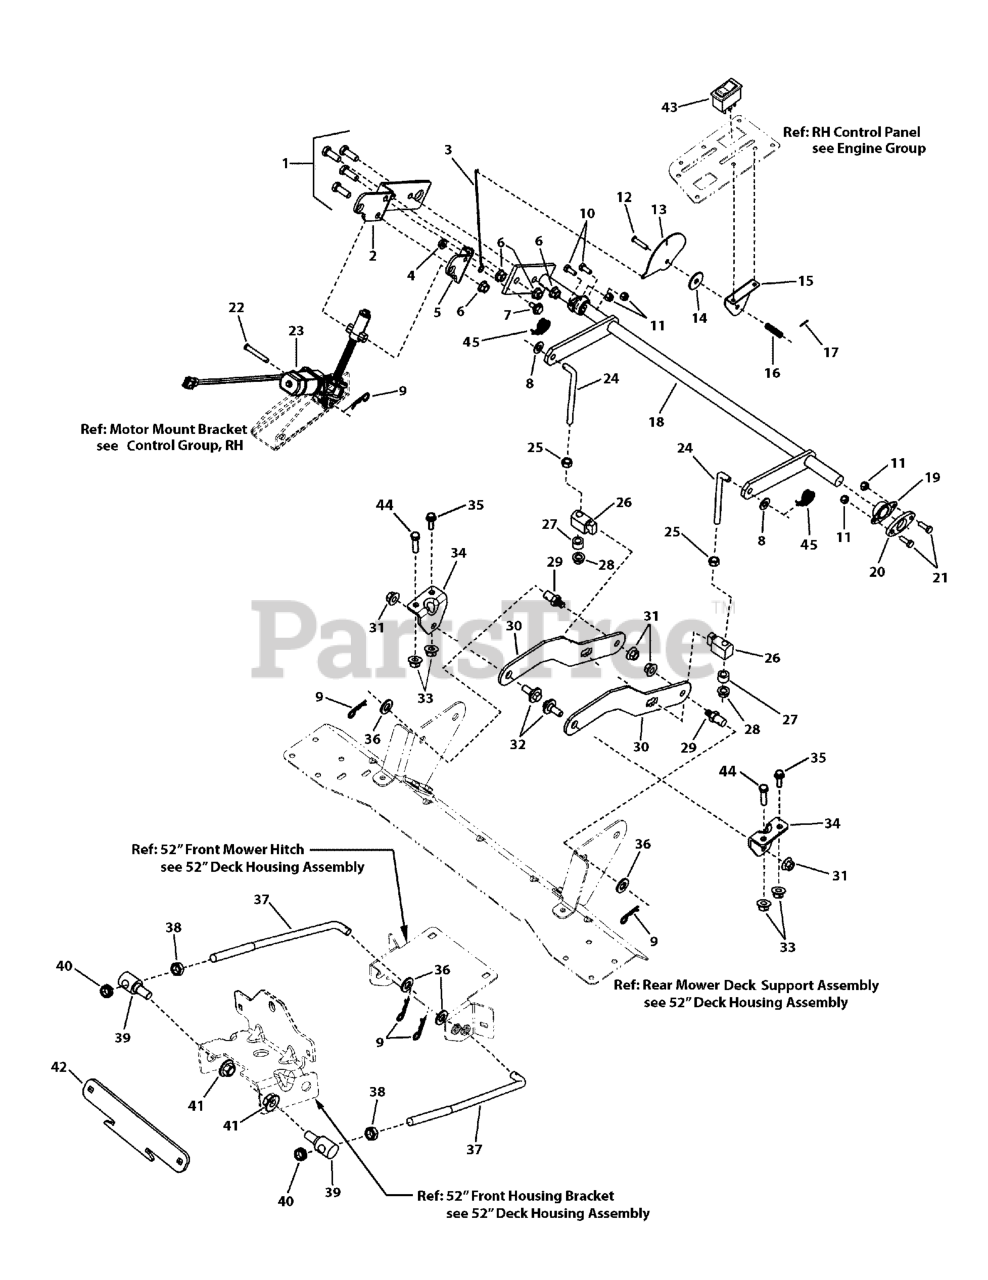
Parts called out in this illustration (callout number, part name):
1	SCREW, 3/8-16 x 1" Hex Head Cap, GR 5, YZ
2	BRACKET, Lift, Deck, Primary
3	ROD, Indicator, Height-Of-Cut
4	NUT, 1/4-20 Hex Flange Lock, GR 5, YZ
5	BRACKET, Lift, Deck, Secondary
6	NUT, 3/8-16 Hex Flange lock, YZ
7	SHOULDER BOLT, 1/4-20 x 3/8"
8	WASHER, 3/8" Flat (SAE)
9	HAIR PIN, 3/32 x 1-1/2" YZ
10	SCREW, 1/4-20 x 5/8" Hex Head Cap, GR 5
11	NUT, 1/4-20 Hex Nyloc, YZ
12	CLEVIS PIN, .25 x 1.09
13	LEVER, Indicator, Height-Of-Cut
14	WASHER, 5/16" Nylon
15	BRACKET, Indicator, Height-Of-Cut
16	SPRING, Compression
17	COTTER PIN, .06 x 1/2" YZ
18	WELDMENT, Deck Lift, 38/42
19	BEARING, Flange, .75 ID PM
20	SPACER, Bearing, .25"
21	SCREW, 1/4-20 x 3/4" Hex Head Cap, GR 5 YZ
22	SHEAR PIN, .248 ID x 1-3/4" Long
23	MOTOR, Actuator, Lift, Deck
24	ROD, Mower Lift (3/8-16 thread) Yellow
25	NUT, 3/8-16 Hex, Black
26	TRUNNION, Powdered Metal, Yellow, Regent
27	SPACER, .385 ID x .6697 OD x .455 Long, PM Yellow
28	NUT, 3/8-16 Hex Flange Esna, Black
29	PIN, 3/8-16 Threaded Shoulder
30	BAR, Rear Lift
31	NUT, 3/8-16 Hex Flange Center Lock, Zinc Plated
32	SHOULDER BOLT, 3/8-16 x .94, BZ
33	NUT, 5/16-18 Flange Lock, YZ
34	BRACKET, Deck Hanger
35	BOLT, 5/16-18 x 5/8" Hex Flange lock, GR 5, YZ
36	WASHER, 1/2" Flat (0.51 ID x 1.00 OD x .10 Thick) Black
37	ROD, Front Bail (1/2-13 thread) MWR
38	NUT, Hex Jam, 1/2-13
39	TRUNNION, Unthreaded
40	NUT, Hex Lock, 1/2-13
41	NUT, Hex Flange, Two-Way Lock, 1/2-13
42	SUPPORT, Hanger
43	SWITCH, Rocker Electric Height-Of-Cut
44	CAPSCREW, Hex Head, 5/16-18 x 1
45	COTTER PIN, 3/8" Self Lock
